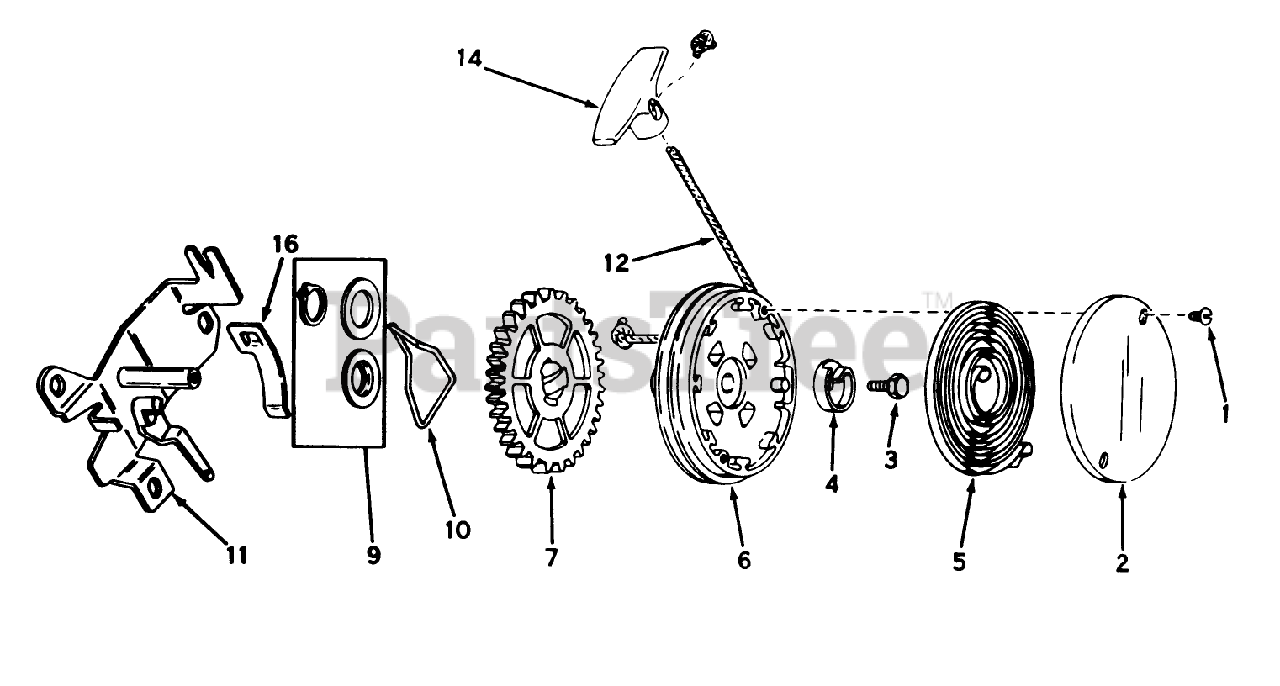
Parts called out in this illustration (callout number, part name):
1	Screw
2	Cover, Spring
3	Screw, Hex Washer Head
4	Hub Spring
5	Spring, Rewind
6	Pulley Assy. (Incl. No. 9)
9	Kit, Thrust Wash. Snap Rg.
10	Brake
11	Bracket Assy., Mounting
12	Rope-Starter
14	Handle-Starter
16	Clip Rope
